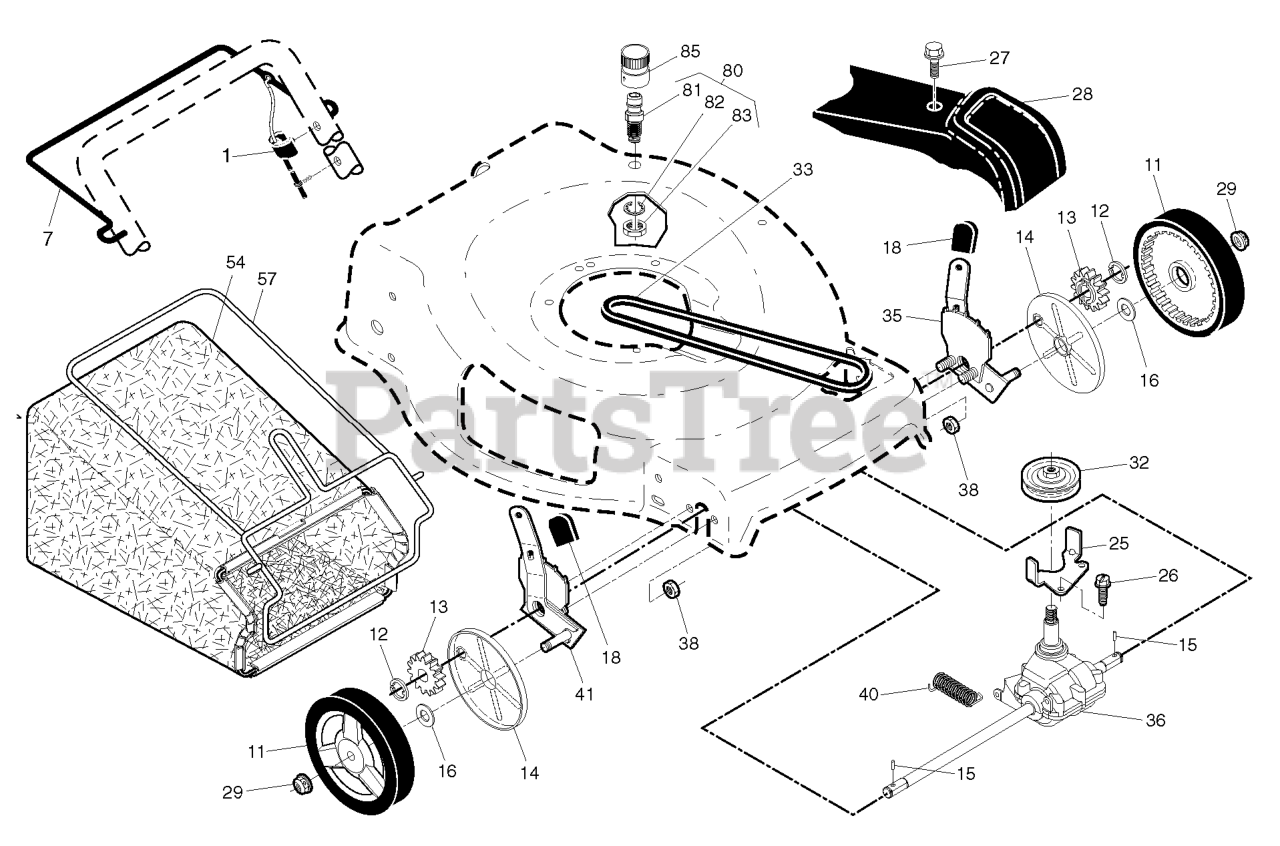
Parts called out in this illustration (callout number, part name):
1	CABLE.DRIV.DUAL.LEVER.BAIL.FGD
7	BAIL.CONT.DR.S/S.ROUND.BLACK
11	WHEEL.8X1.75.H3SPK.RAD3.GY.BU3
12	E-RING 7/16 RE
13	PINION.14.TEETH.FGD
14	COVER.DUST.WHEEL.INNER.WALK
15	PAWL, DRIVE
16	WASHER FLUT
18	SELECTOR KNOB
25	BRACKET.BELT.GUIDE.22+FGD.BZP
27	SCREW, HEX HD TAPPING #10-24 1
28	COVER.DR.22.MB LABEL HUSQ E/F
29	NUT.HEX.FLANGE.3/8-16.LO(3 2)
32	PULLEY.DRIVEN.EZ/VARI (2 2MC)
33	BELT.DRIVE.FGD.
35	ADJUSTER.ASM.22+FGD.LF /AWD LT
36	RP.TRANSMISSION.22+.FWGD.SS
38	NUT.FLANGE.1-4-20-SERR
41	ADJUSTER.ASM.22+FGD.RF /AWD RT
54	GBAG.A361029ER.HUSQ.GRY/SIL
57	FRAME.GBAG.22+.BLK
80	KIT.WASH-OUT.PORT.ZINC.WALK
81	WASHOUT.PORT.ZINC.RGD.22+
82	WASHER.LOCK.INTERNAL.TOOTH
83	LOCKNUT.HEX.WITH.O-RING
85	COUPLING.QUICK CONNECT
